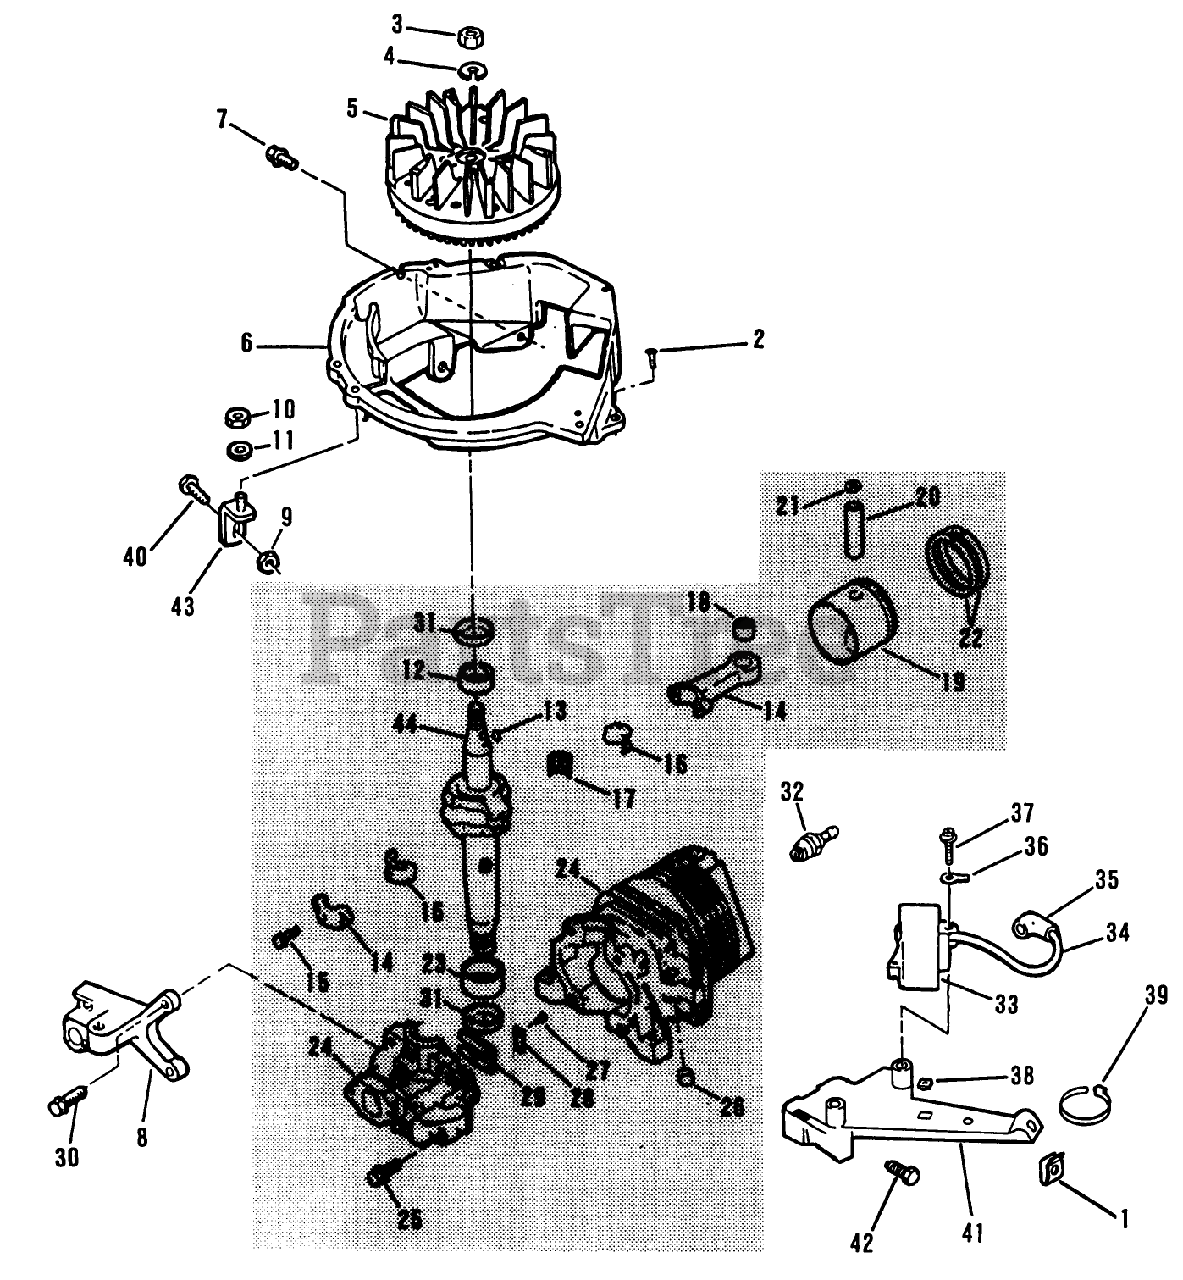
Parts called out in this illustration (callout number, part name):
1	NUT-SPEED
2	SCREW F
3	NUT
5	FLYWHEEL ASSY F
7	SCREW-SEMS
8	BRACKET-BRAKE F
9	NUT-LOCK F
10	LOCKNUT E
11	WASHER S
12	BEARING V
13	KEY
15	SCREW-HSH
16	LINER ASM
17	BEARING-NEEDLE
18	BEARING AY F
21	RING-RETAINING
23	BEARING V
25	SCREW-H.W.HD. F
26	PLUG-CORE VF
27	SCREW-HH
28	PLATE-BACKUP, REED
30	SCREW
31	SEAL-OIL
34	HT LEAD&COVER XEV
36	TERMINAL S
38	NUT-CLIP
40	BOLT F
43	BRACE AY F
